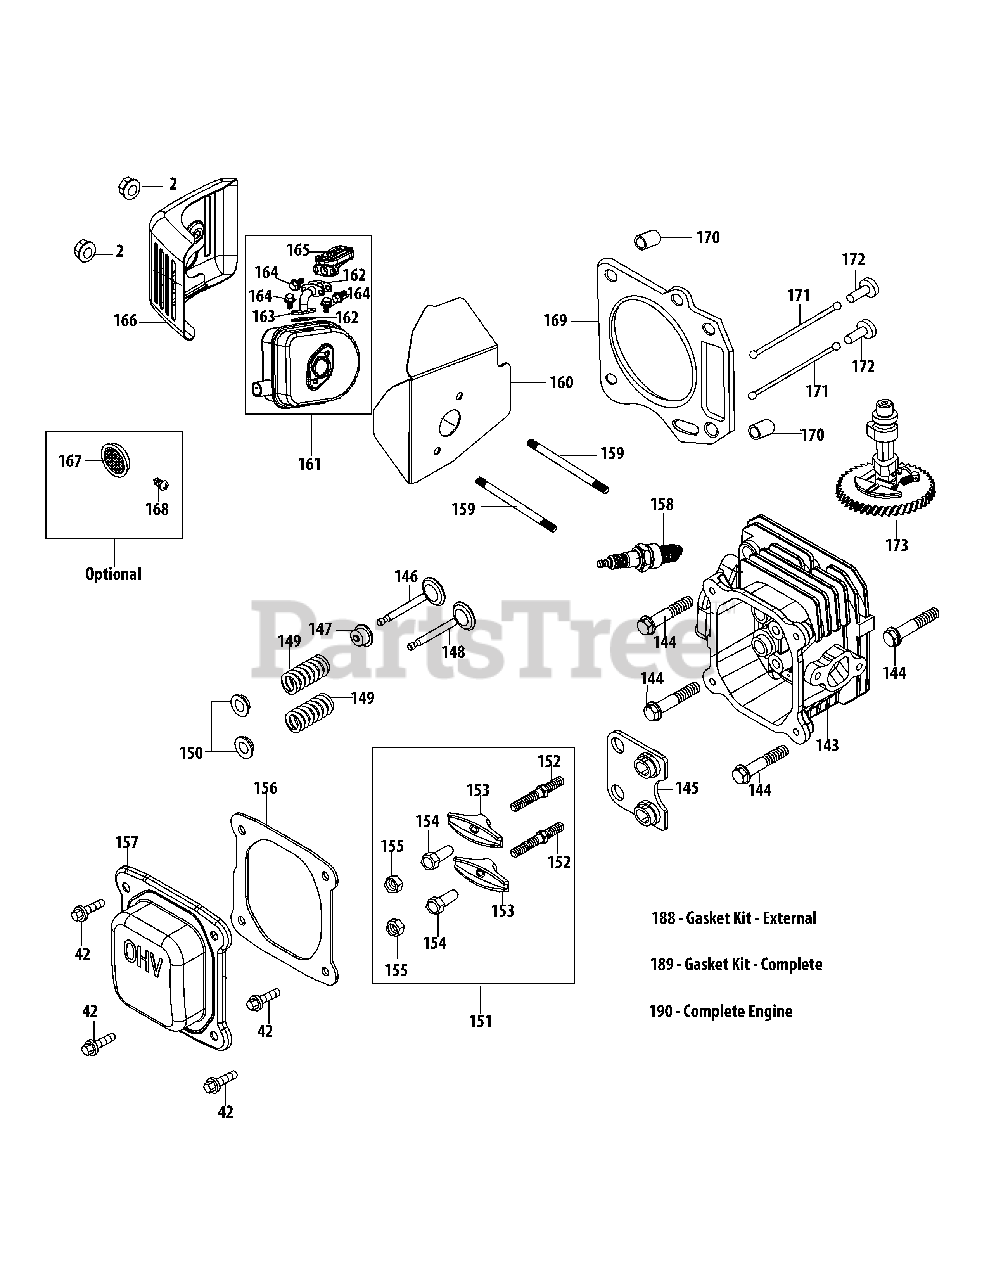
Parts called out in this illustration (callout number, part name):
2	Nut M6X10Mm
143	Cylinder Head Service Kit
143	Cylinder Head Ass'y
144	Bolt M8X54 Cylinder Head
145	Push Rod Guide
146	Intake Valve
147	Intake Valve Seal
148	Exhaust Valve
149	Valve Spring
150	Valve Spring Retainer
151	Rocker Arm Assembly
152	Rocker Arm Stud
153	Rocker Arm
154	Fulcrum Nut
155	Jam Nut
156	Valve Cover Gasket
157	Valve Cover
158	Spark Plug/F6Rtc
159	Muffler Stud M6X95
159	Muffler Stud Assemlby
160	Muffler Gasket
161	Muffler Assembly
162	Secondary Air Valve Gasket
163	Secondary Air Tube
164	Bolt M6×12 Secondary Air Tube/Valve
165	Secondary Air Valve
166	Muffler Shield
167	Spark Arrestor
168	Spark Arrestor Screw
169	Cylinder Head Gasket
170	Cylinder Head Dowel Pin 10×16
171	Push Rod
172	Tappet
173	Camshaft Assembly
188	Gasket Kit - External
189	Gasket Kit - Complete
190	Complete Engine
